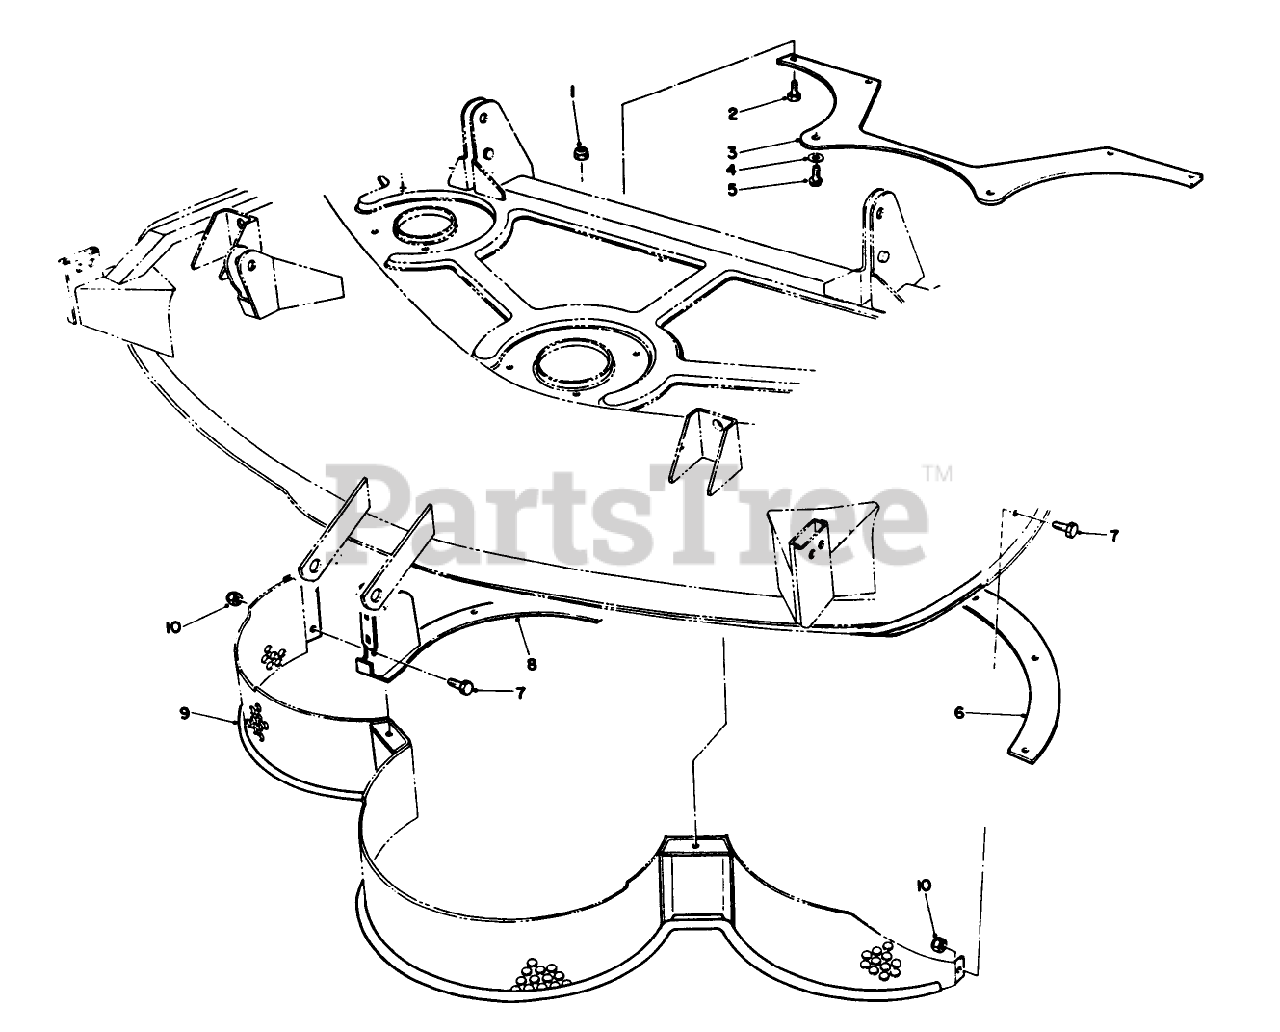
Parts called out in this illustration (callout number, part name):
1	NUT-LOCK, NI
2	SCREW-HH
4	WASHER-FLAT
5	SCREW-HHFTF
7	SCREW-HH
10	NUT-LOCK, NI
